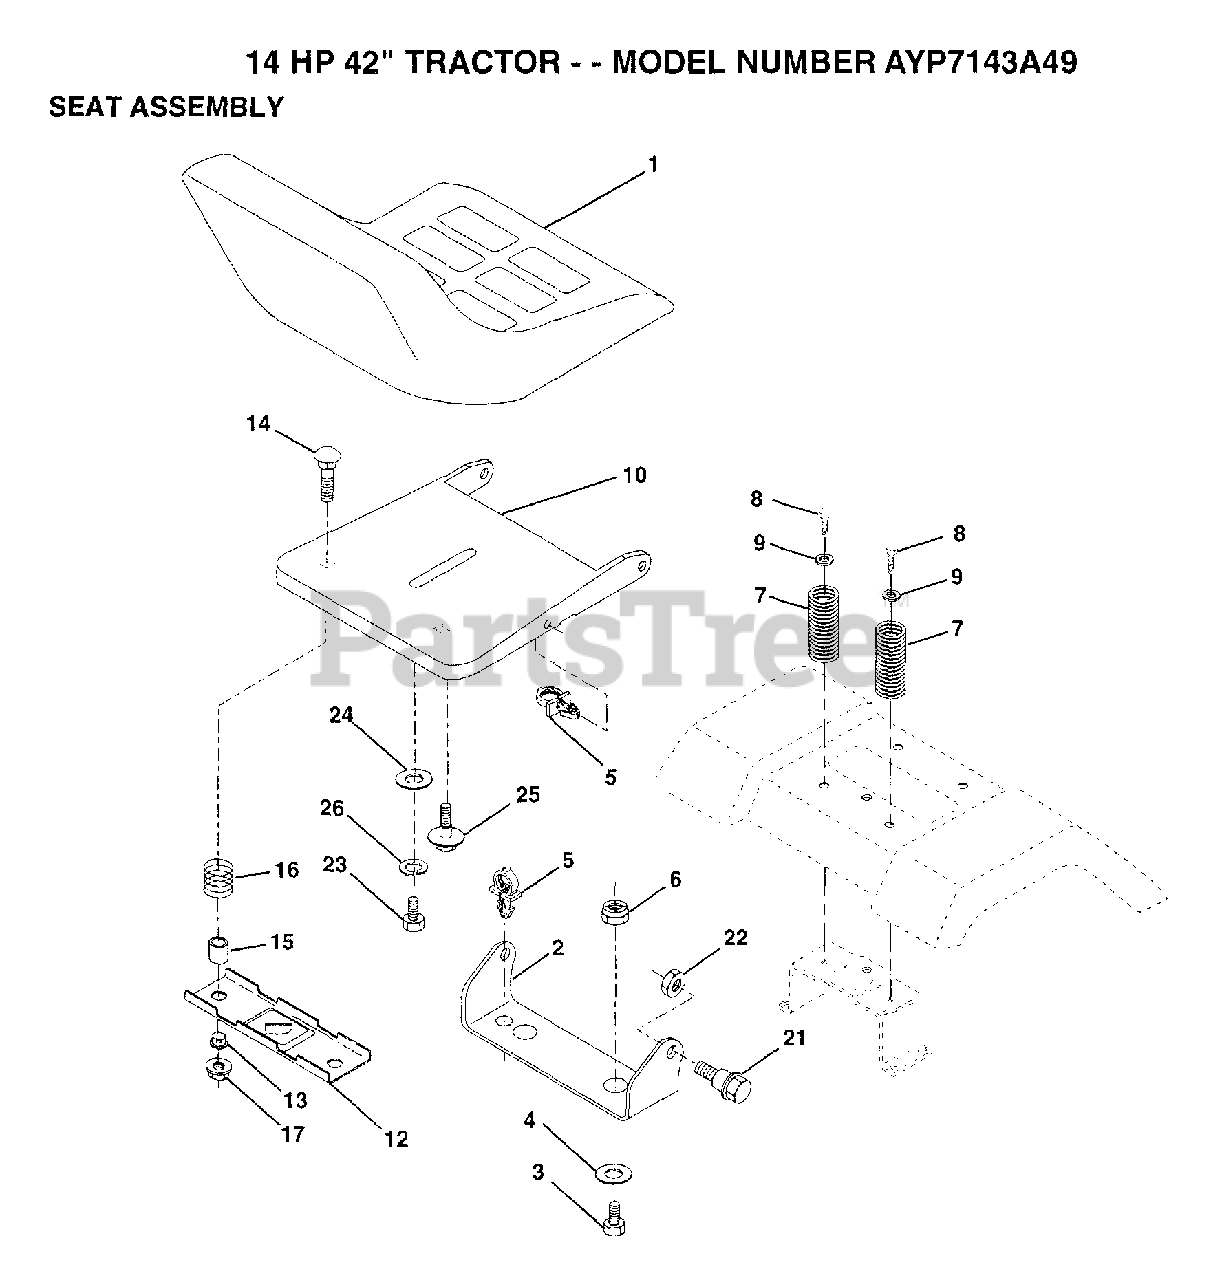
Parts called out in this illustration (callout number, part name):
2	BRACKET PVT SEAT
4	WASHER PM
5	CLIP PUSH - IN
6	NUT
7	SPRING COMPRESSIO
8	SCREW GTV
9	WASHER
12	BRKT SWITCH
13	BUSHING
15	SPLIT SPACER
16	SPRING
21	BOLT.SHLD.5/16-18
23	BOLT
24	WASHER
25	"BOLT,SHOULDER"
26	LOCKWASHER
